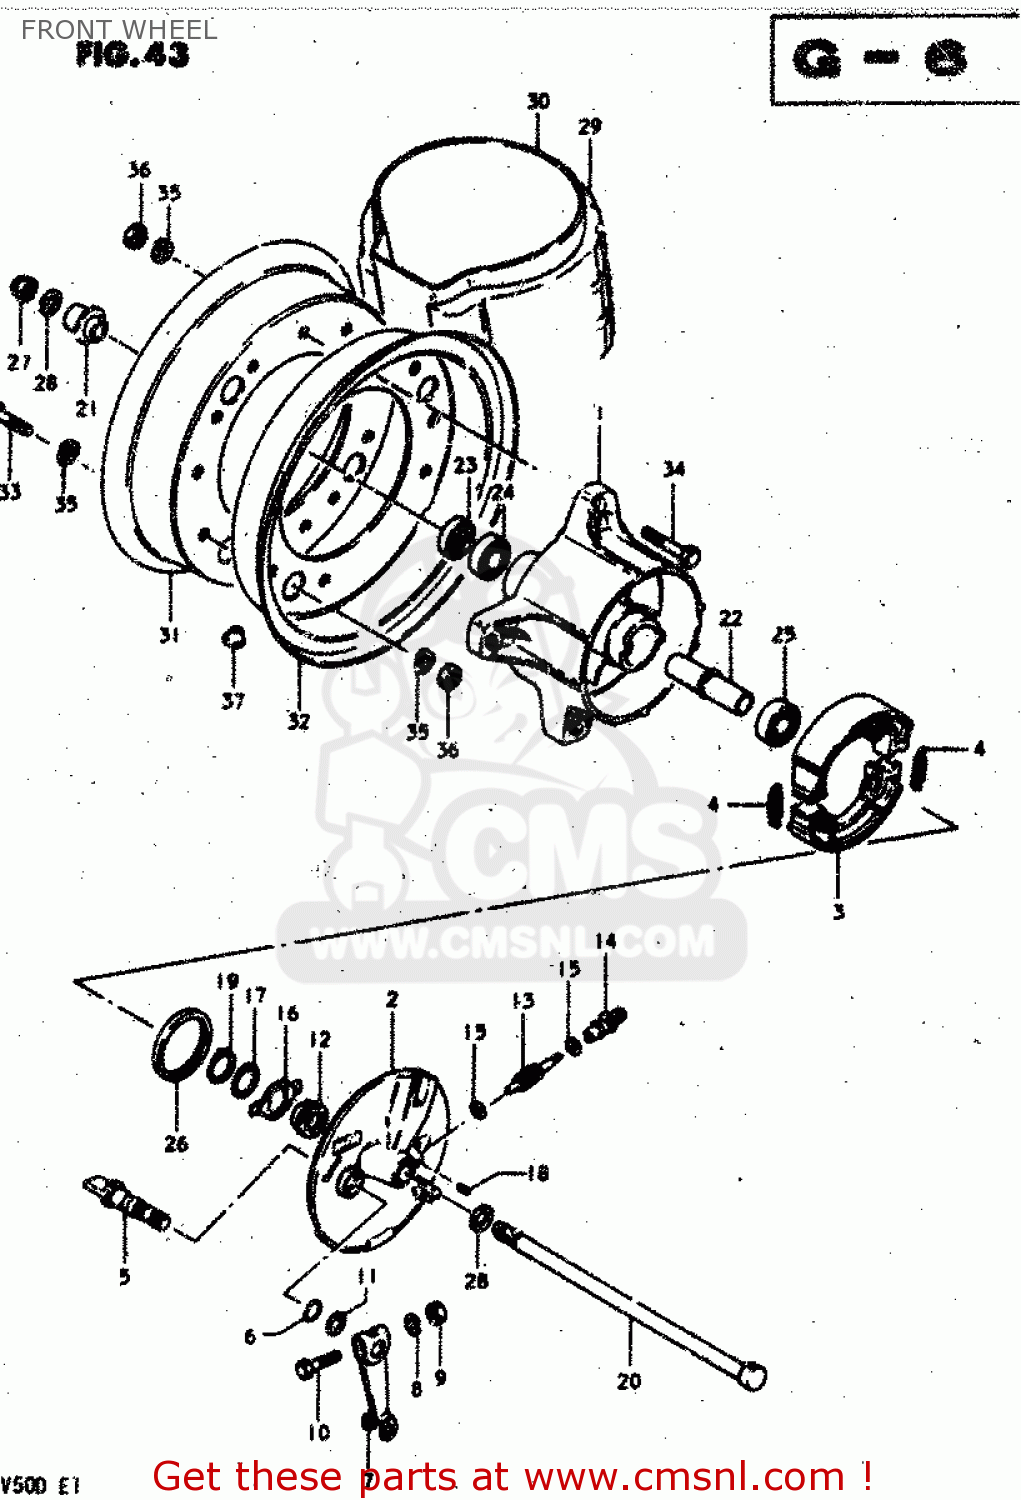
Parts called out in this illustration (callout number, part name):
1	DRUM,FRONT HUB
2	PANEL,FRONT HUB
3	SHOE,BRAKE
4	SPRING(L:34)
5	CAM,FR BRAKE
6	O RING(D:2.5,ID:11.4)
7	LEVER,FR BRAKE CAM
8	WASHER
9	NUT
10	BOLT
11	WASHER(12.5X20X1)
12	GEAR, SPEEDOMETER (NT:20)
13	PINION,SPEEDOMETER
14	BUSH,METER GEAR OUTER
15	WASHER (5.1X9X0.4)
16	DRIVER,SPEEDOMETER GEAR
17	WASHER(18.5X24X1)
18	SCREW
19	CIRCLIP
20	AXLE, FRONT
21	SPACER, FRONT AXLE RH
22	SPACER,FRONT HUB BEARING
23	SEAL,OIL(18X32X7)
24	BEARING
25	BEARING
26	OIL SEAL (43X58X7)
27	NUT
28	WASHER
29	TIRE(5.40 10)
30	TUBE,INNER
31	RIM,WHEEL,R
32	RIM,WHEEL,OUTER
33	BOLT
34	BOLT
35	LOCK WASHER
36	NUT
37	BUSHING
